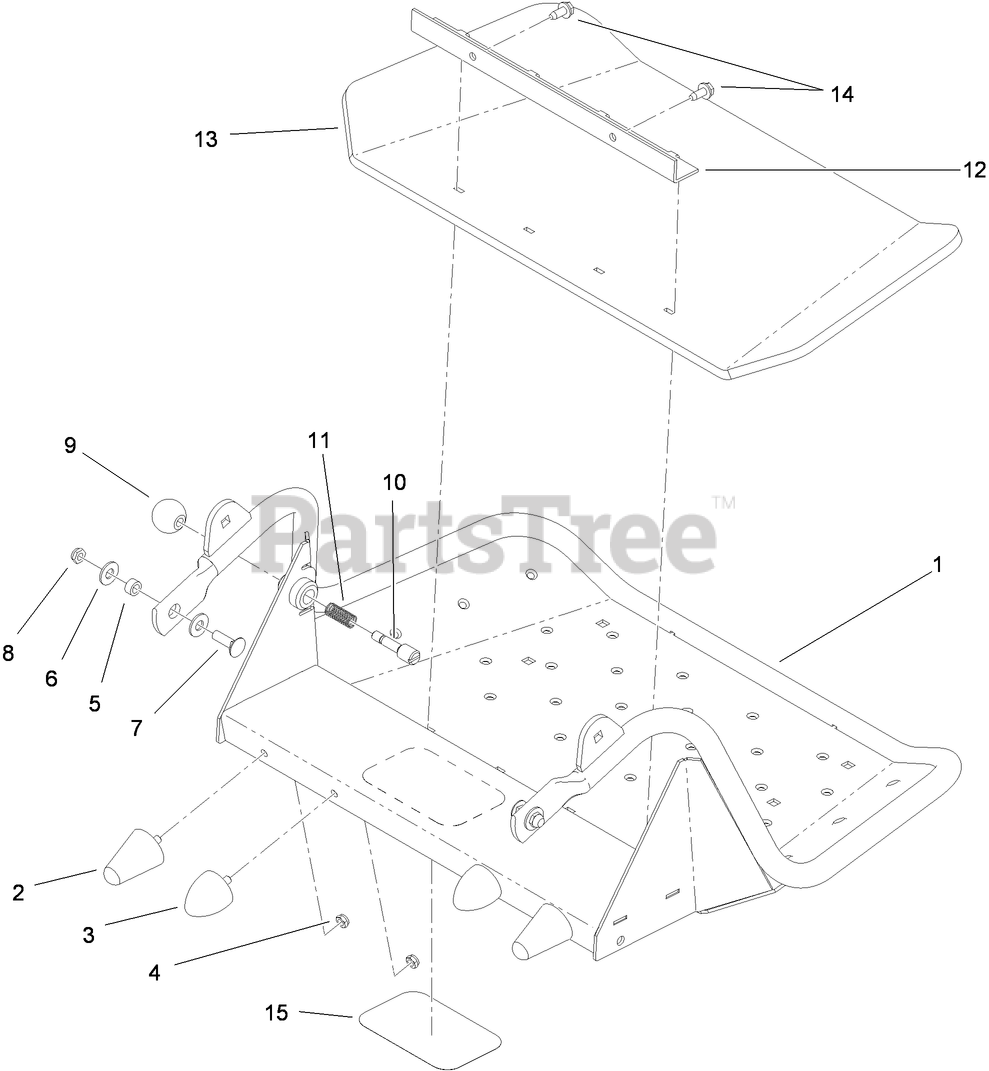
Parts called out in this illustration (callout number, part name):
1	PLATFORM
2	BUMPER-RUBBER
3	BUMPER-RUBBER
4	NUT-LOCK, NI
5	SPACER
6	WASHER-FLAT
7	BOLT-CARR
8	NUT-LOCK, NI
9	KNOB-BALL
10	PIN-LATCH
11	SPRING
12	CLAMP-SHIELD
13	MAT-FOOT
14	SCREW-HWHTF
15	DECAL
